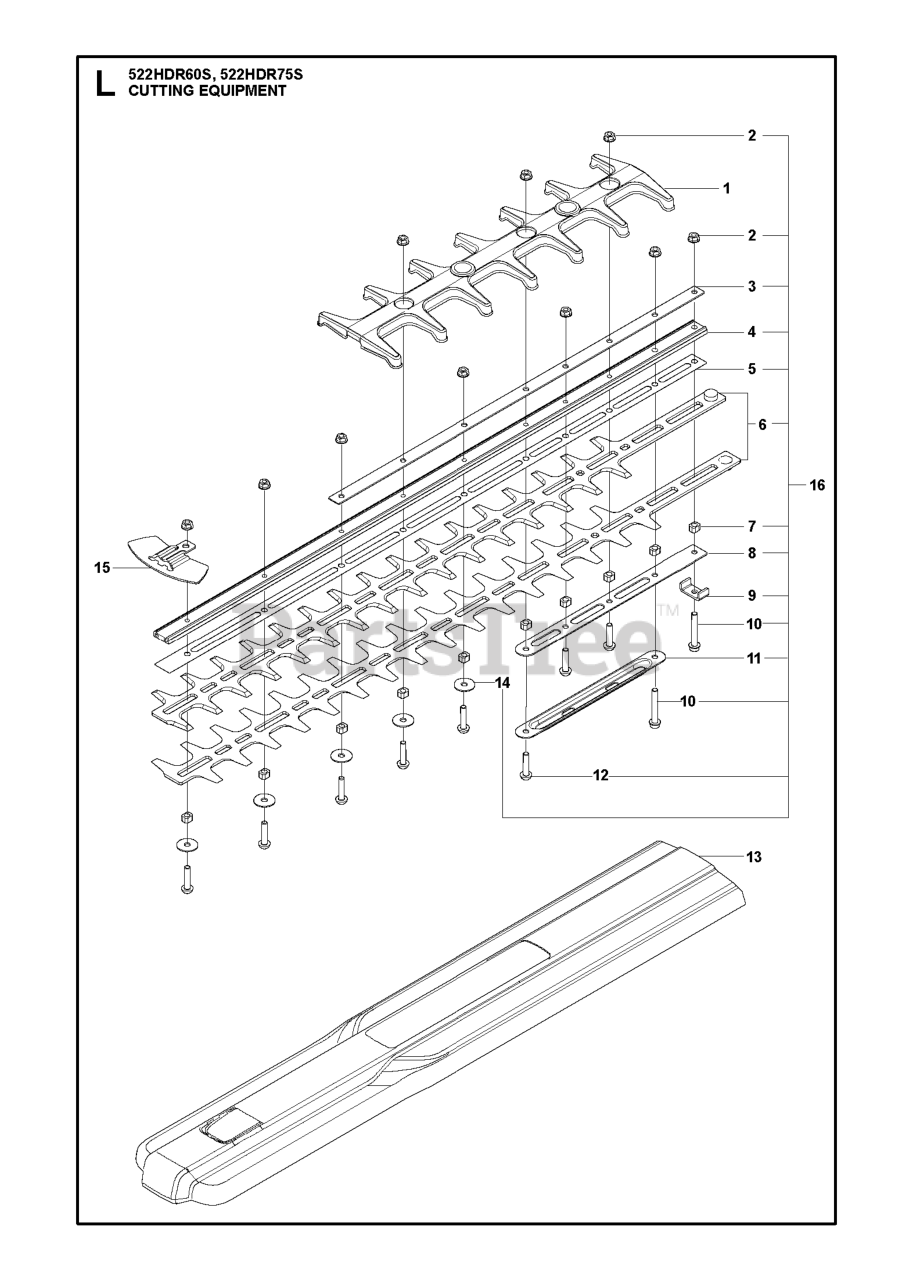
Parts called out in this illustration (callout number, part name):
1	Protection
2	NUT HEXAGON LOCK WITH FLANGE M
3	BAR PLATE UPPER
4	Guide Bar
4	GUIDE BAR HD/HS60
5	WEAR PLATE
6	BLADE KIT
7	SPACER CUTTING DECK
8	BAR PLATE LOWER
8	BAR PLATE
11	BAR PLATE LOWER
12	SCREW HEXALOBULAR SOCKET BUTTO
13	TRANSPORT GUARD HD75 HUSQVARNA
13	TRANSPORT GUARD HUSQVARNA GRE
14	WASHER PLAIN 5.5X19X1.2 ST TBO
15	PROTECTION BLADE TIP
16	CUTTING DECK KIT HDR60
16	CUTTING DECK KIT HDR75
